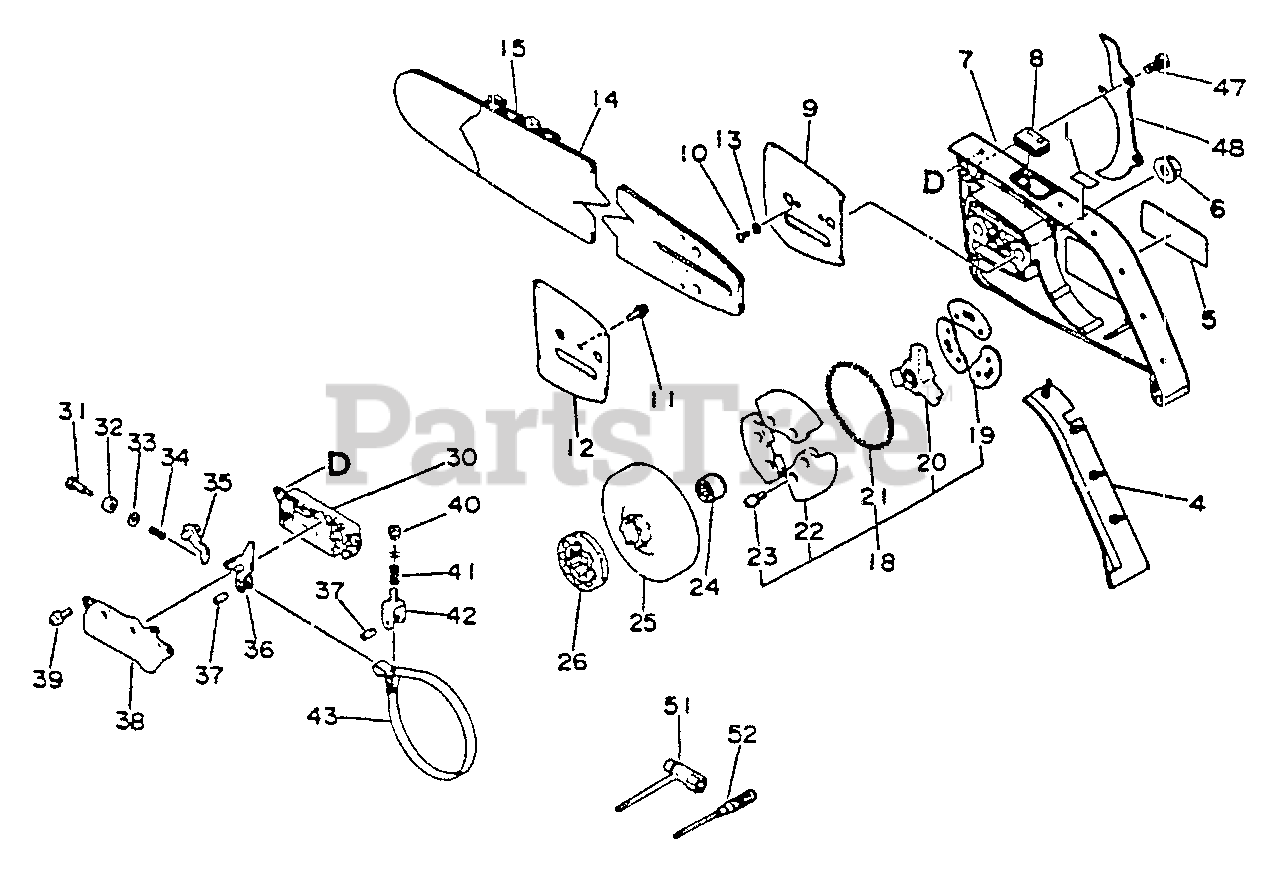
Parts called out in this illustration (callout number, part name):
1	LABEL, CAUTION
5	LABEL, ECHO
6	NUT, FLANGE M8×1.25
7	GUARD, SPROCKET
9	PLATE, GUIDE - OUTER
10	SCREW 3×6
11	SCREW - 4×10
12	PLATE, GUIDE - INNER
14	GUIDE BAR
18	CLUTCH ASSY
19	PLATE, CLUTCH
20	HUB, CLUTCH
21	SPRING, CLUTCH
22	CLUTCH SHOE SET
23	SCREW - 4×8
24	BEARING, NEEDLE
25	DRUM, CLUTCH
26	SPROCKET, RIM 3/8"×7T
30	COVER, BRAKE
34	SPRING ,BRAKE
35	STOPPER, BRAKE
36	LEVER, BRAKE
37	PIN, SPRING
39	SCREW - 4×10
42	ADJUSTER, BRAKE BAND
43	BAND, BRAKE
48	SPIKED BUMPER KIT
51	T-WRENCH 13×19×180
52	SCREWDRIVER, PHILLIPS
